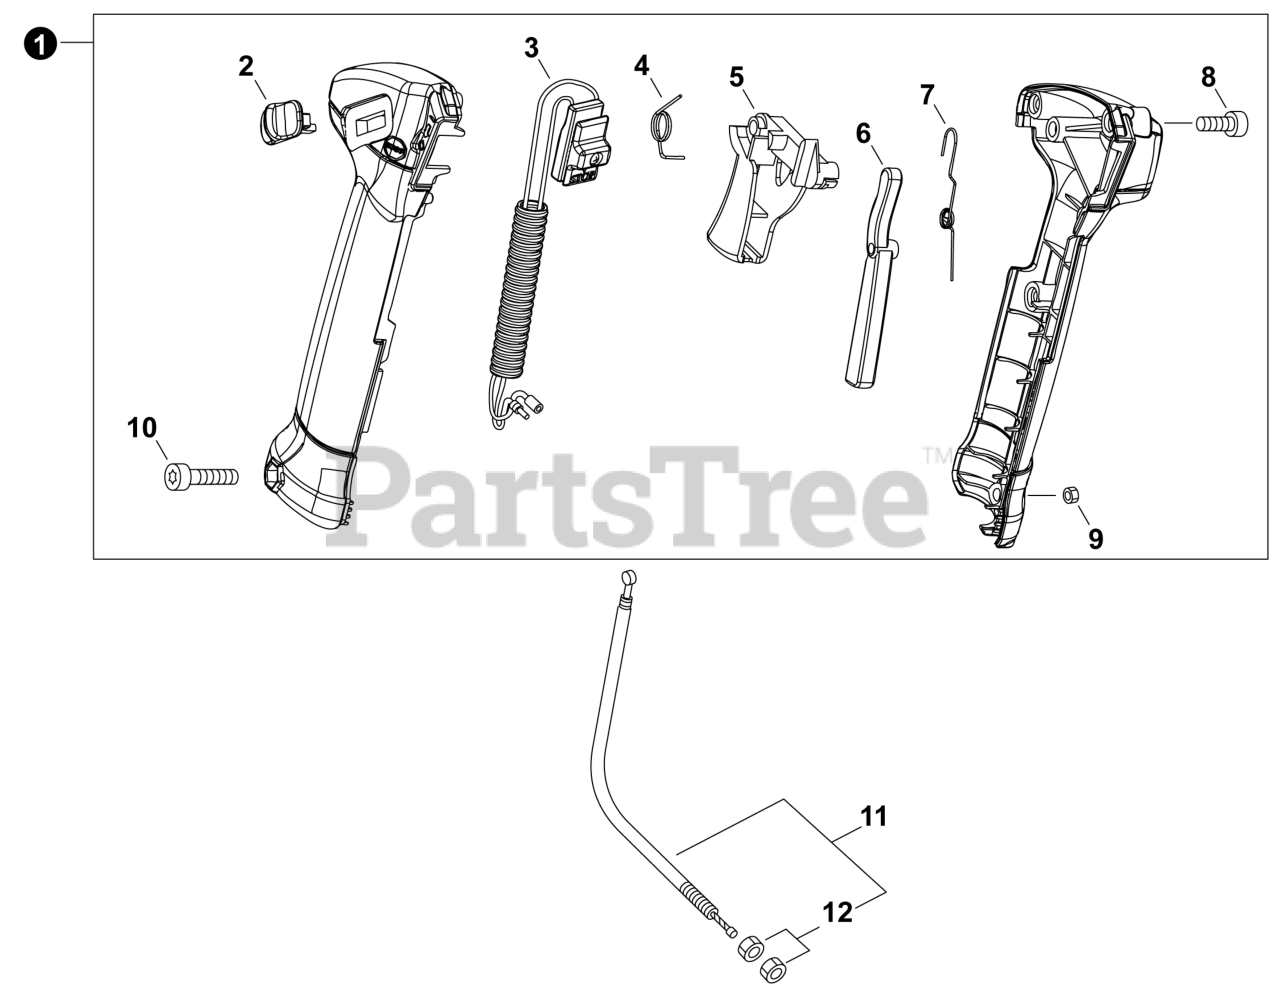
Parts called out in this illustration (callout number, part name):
1	CONTROL HANDLE ASSY
2	LATCH, THROTTLE
3	SWITCH ASSY, ON-OFF
4	SPRING, TORSION
5	CONTROL, THROTTLE
6	LOCKOUT, THROTTLE
7	SPRING, TORSION
8	BOLT, TORX 4x16
10	BOLT, TORX 5x35
11	CABLE, THROTTLE
